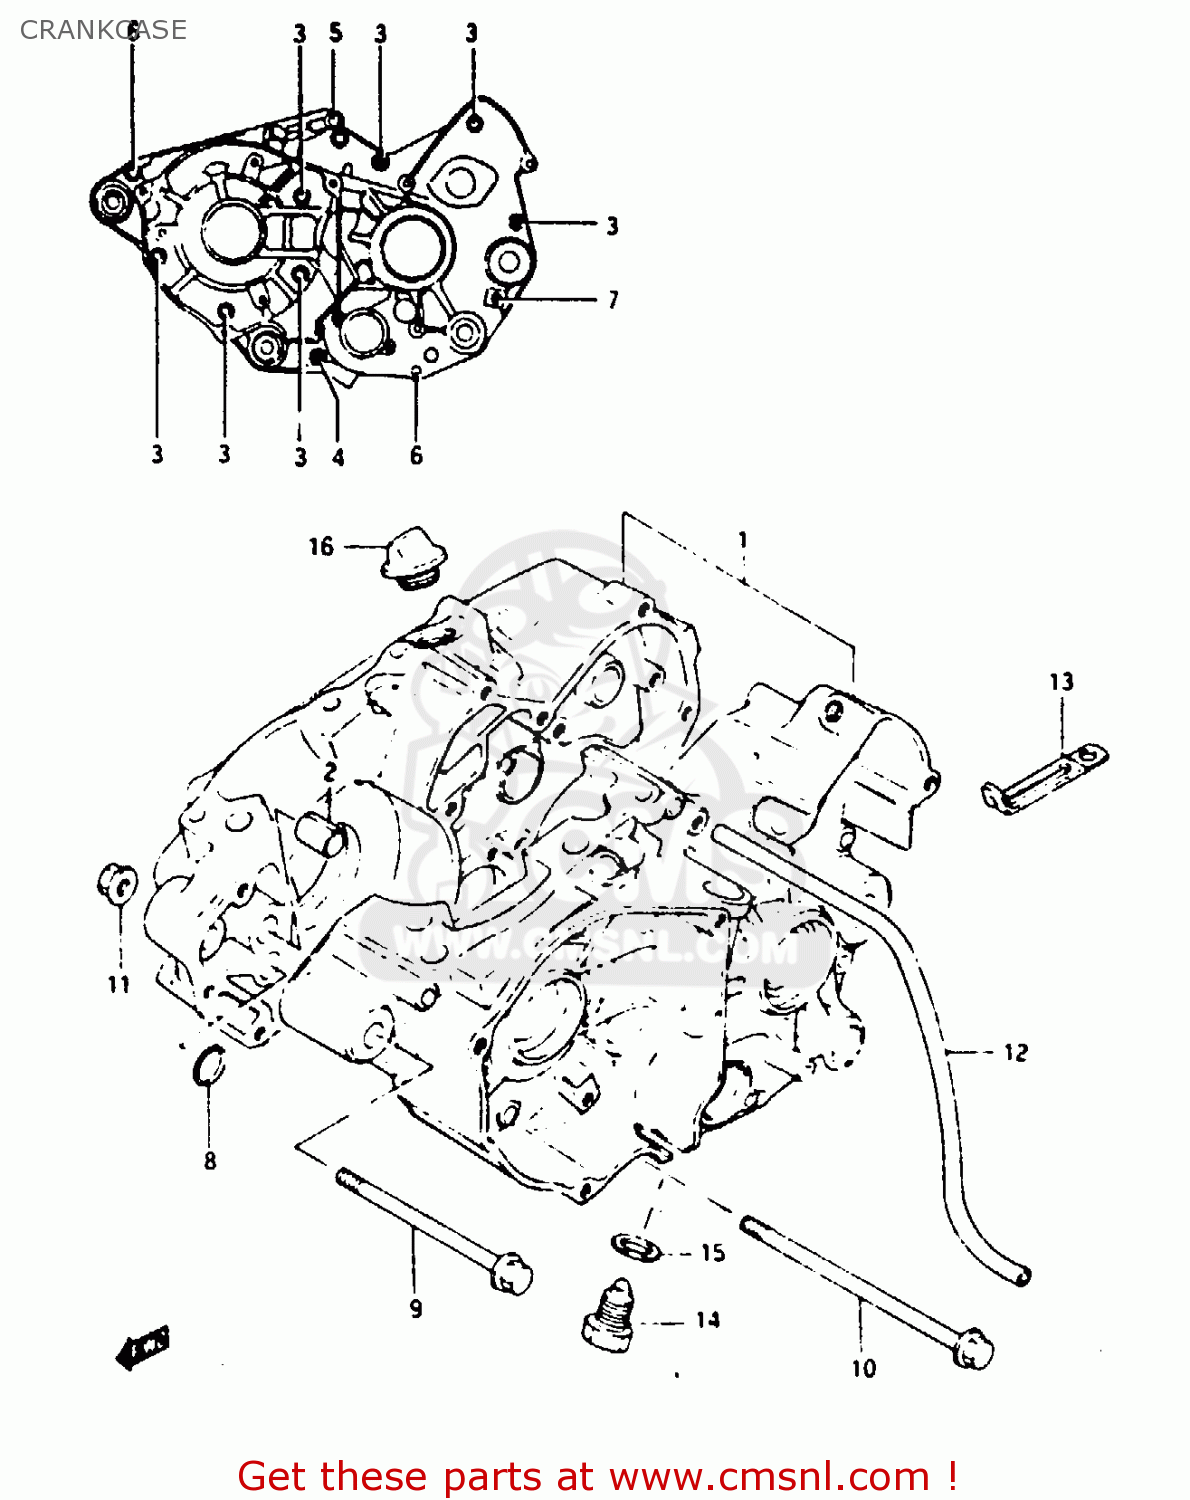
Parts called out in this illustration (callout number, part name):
1	CRANKCASE SET
2	PIN
3	SCREW
4	SCREW (6*60)
5	SCREW
6	SCREW
7	SCREW (6*75)
8	O RING(D:1.9,ID:15.8)
9	BOLT(8X100)
10	BOLT(8X125)
11	NUT
12	HOSE
13	CLAMP
14	PLUG
15	GASKET(14X19.2X2) (NAS)
16	PLUG SET
